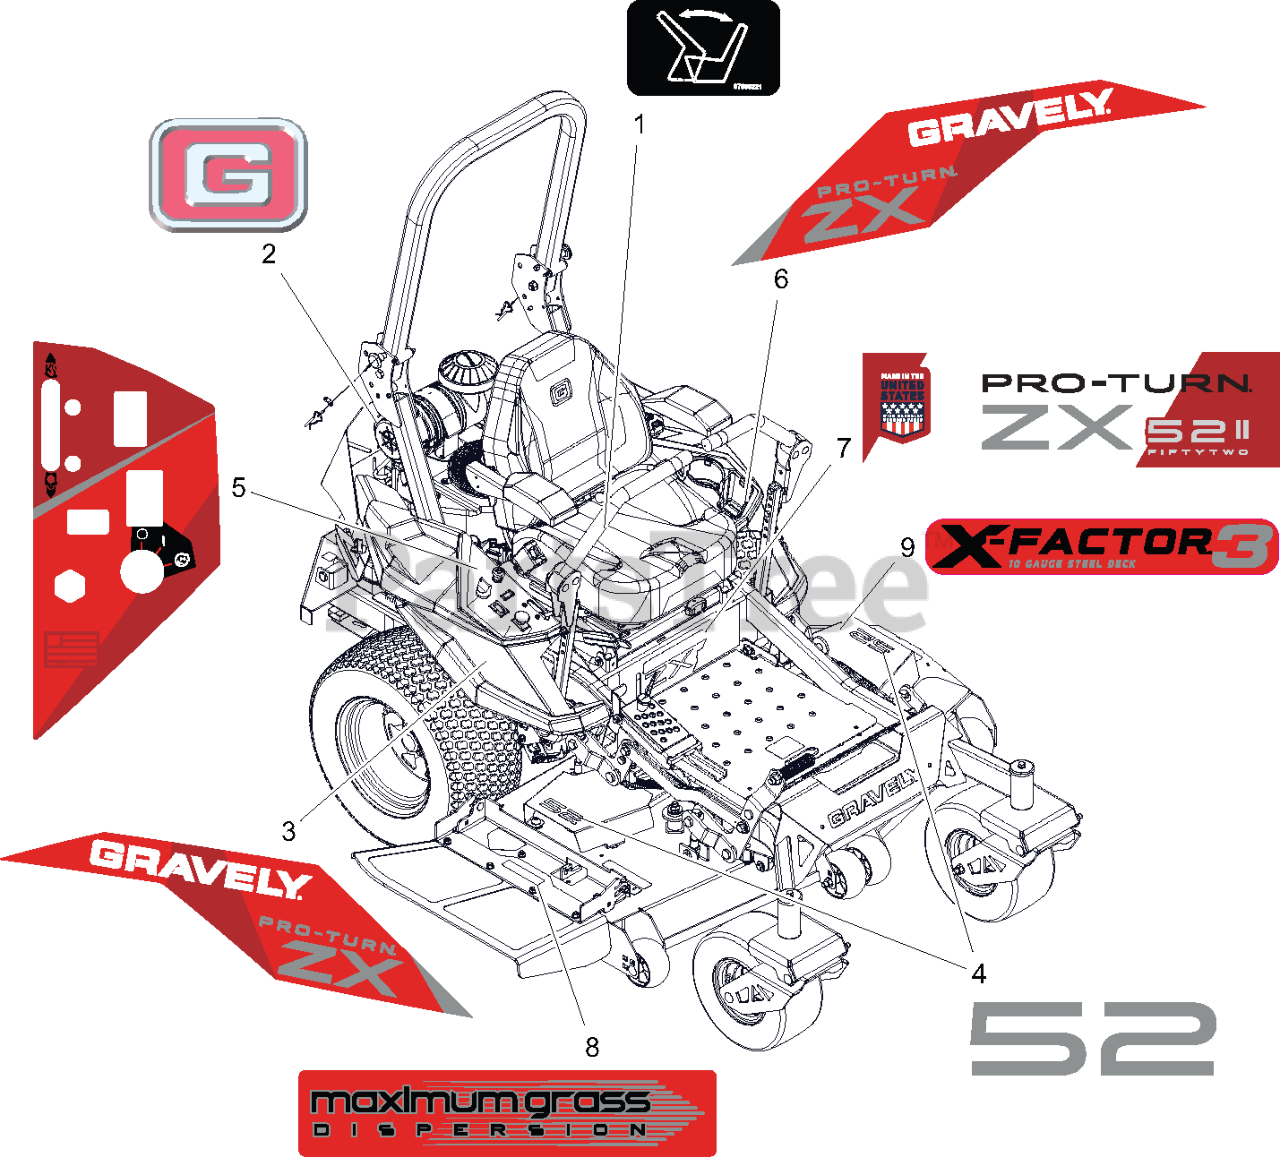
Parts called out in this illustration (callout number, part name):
1	DECAL - SEAT RELEASE
2	DECAL, GRAVELY BRAND
3	DECAL, FENDER RH - PTZX
4	DECAL, DECK - 52
5	DECAL, CONTROL PANEL
6	DECAL, FENDER LH - PTZX
7	DECAL, PTZX - 52
8	DECAL, DECK - MAX GRASS
9	DECAL, X-FACTOR 3
